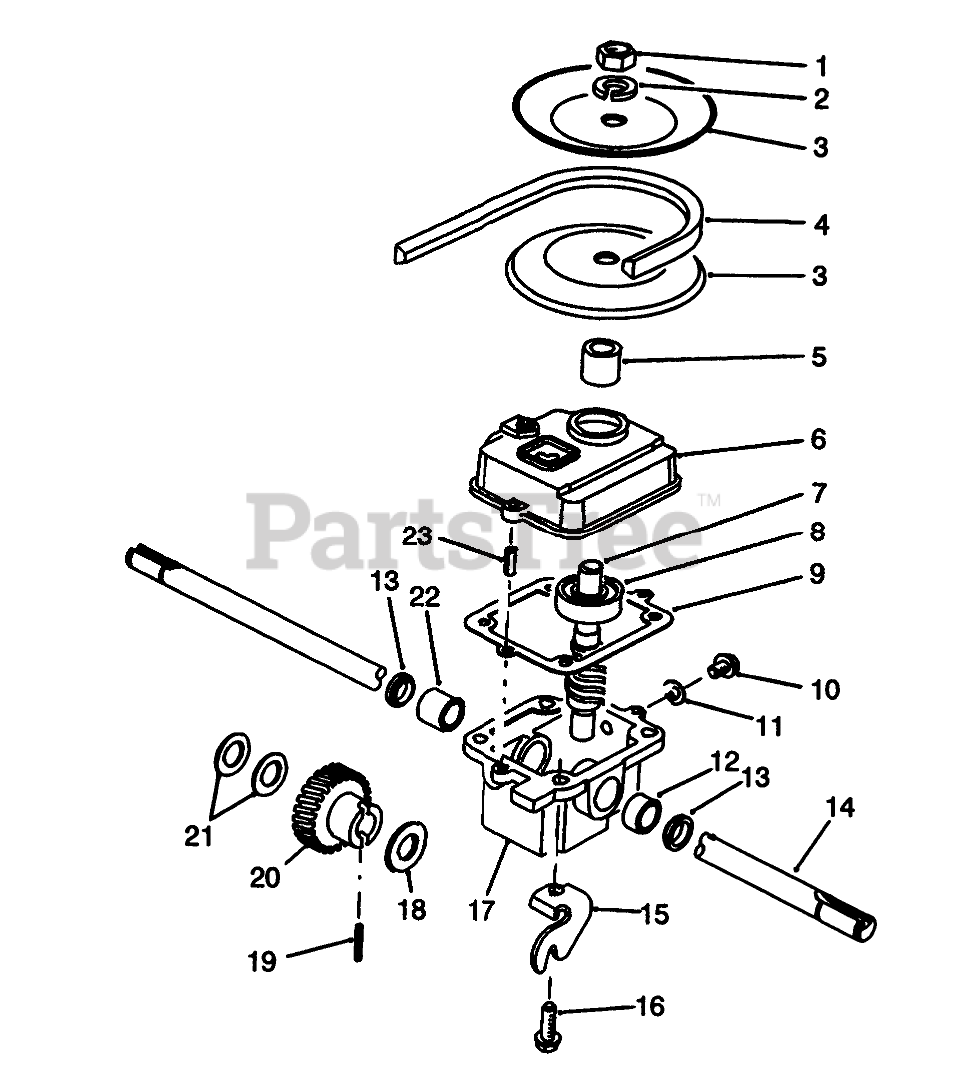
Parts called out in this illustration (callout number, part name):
1	NUT-JAM
2	WASHER-LOCK
3	PULLEY-DRIVEN HALF
4	V-BELT
5	SPACER - PULLEY
6	GEAR CASE COVER
7	SHAFT - WORM
8	BEARING
9	GASKET
10	NYLON SCREW
11	FILL PLUG GASKET
12	BUSHING
13	SEAL-OIL
14	OUTPUT SHAFT
15	TRACTION BRACKET
16	SCREW-HWHTF
17	GEAR CASE
18	THRUST WASHER
19	PIN-SPRING
20	GEAR - HELICAL
21	WASHER-PLAIN
22	BUSHING
23	3/16 X 1/2 ROLL PIN
